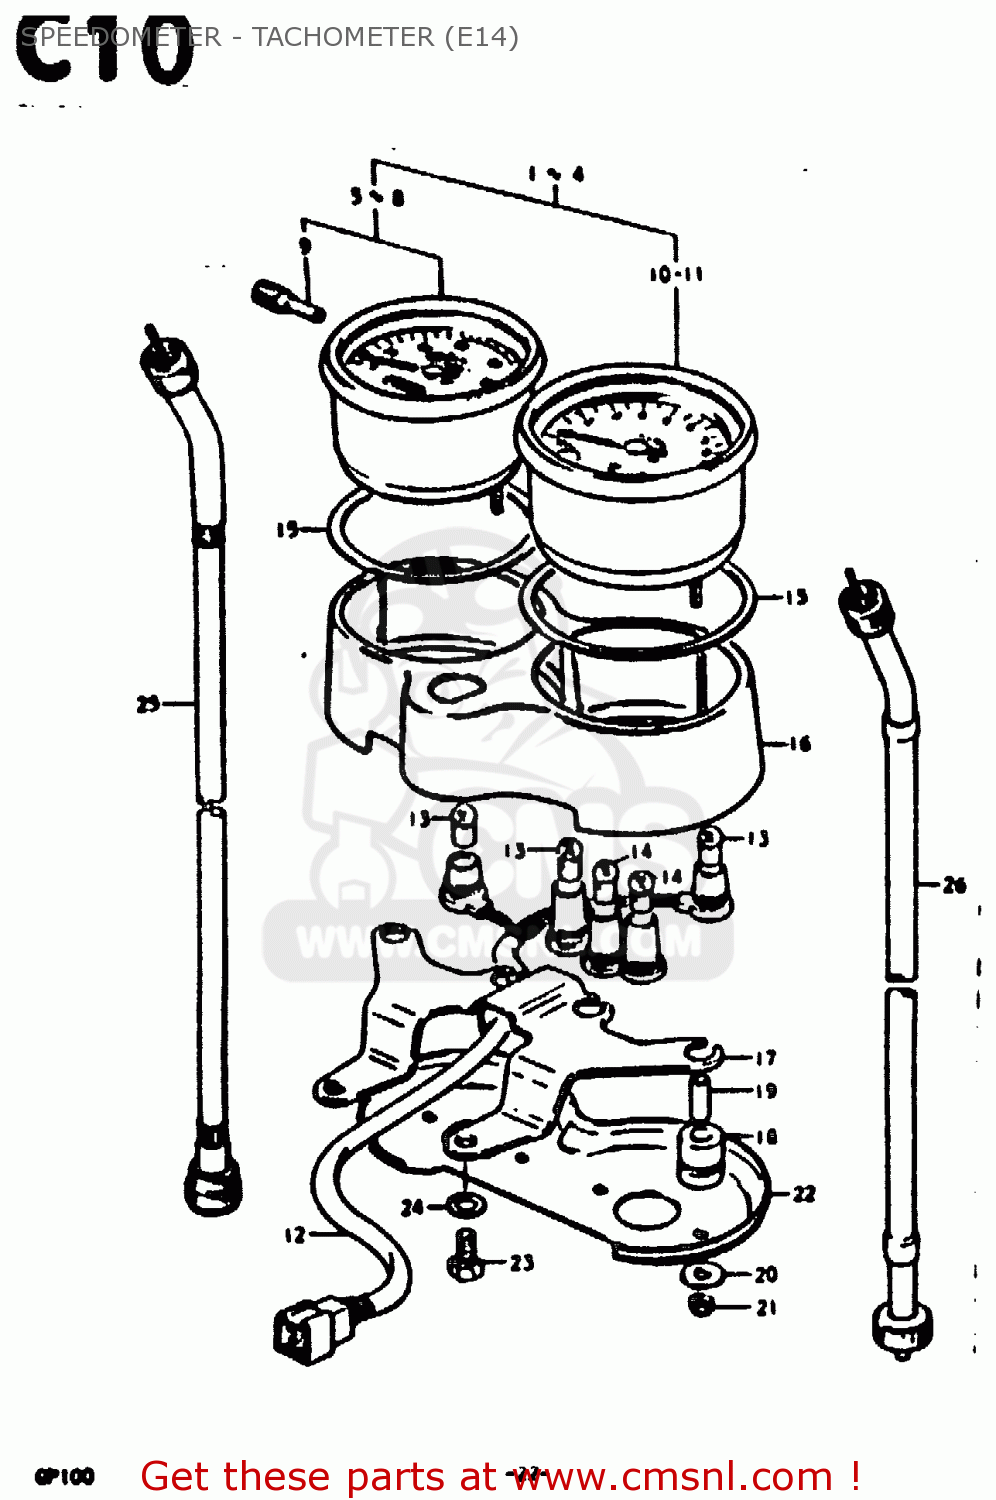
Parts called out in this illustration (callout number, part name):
3	SPEEDOMETER & TACHOMETER ASSY (KILO SCAL
4	SPEEDOMETER & TACHOMETER ASSY (KILO + MI
7	SPEEDOMETER ASSY
8	SPEEDOMETER ASSY
9	KNOB,TRIP METER
10	TACHOMETER ASSY
11	TACHOMETER ASSY
12	SOCKET
13	BULB(6V1.7W,STANLEY,A61A)
14	BULB(6V/3W)
15	GASKET, METER
16	CASE, METER
17	BRACKET
18	CUSHION
19	SPACER
20	WASHER,METER
21	NUT
22	UNDER PLATE
23	BOLT 8X12
24	WASHER
25	CABLE ASSY, SPEEDOMETER
26	CABLE ASSY, TACHOMETER
